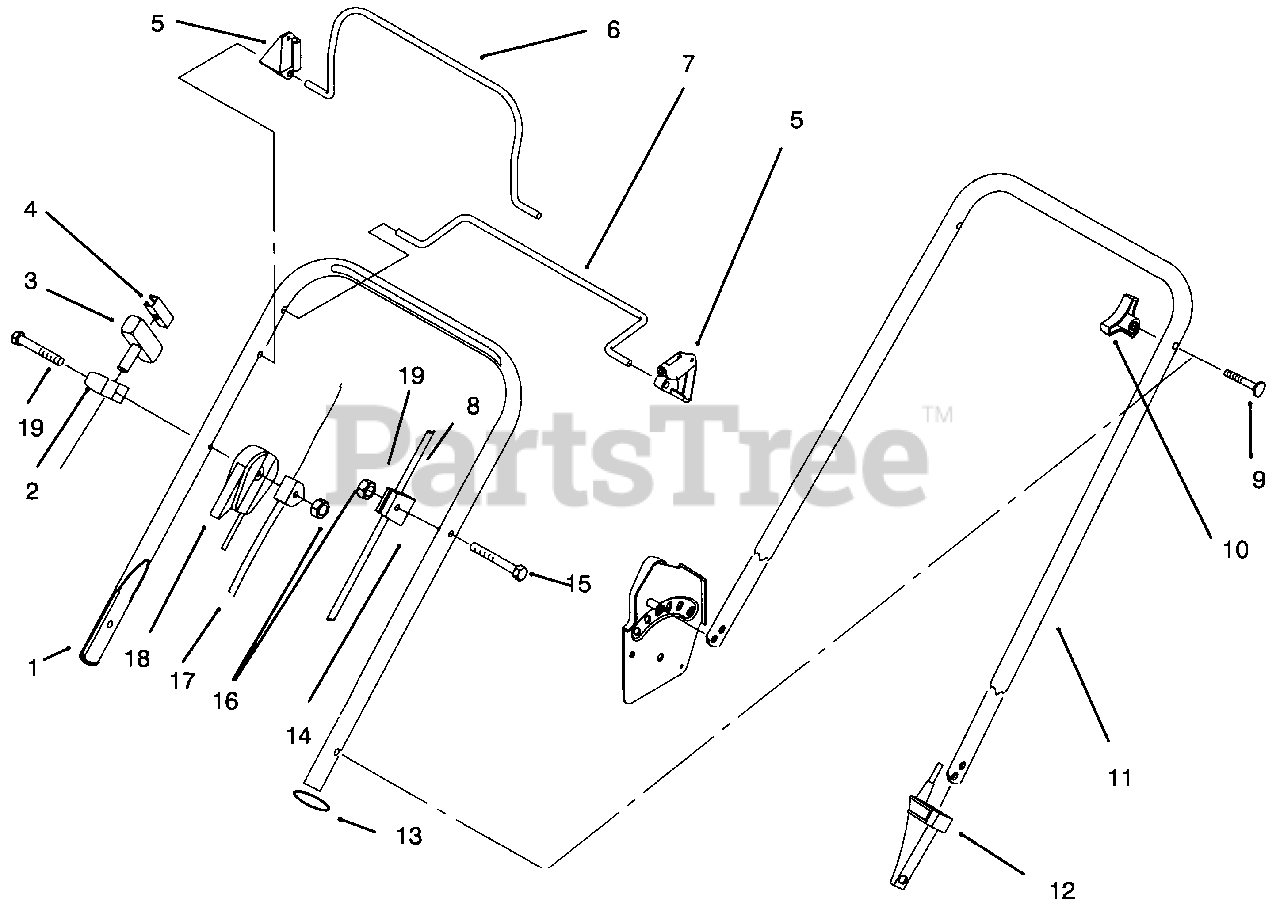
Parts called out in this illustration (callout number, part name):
1	Handle-Upper
2	Guide-Rope
3	Handle-Starter
4	Clip-Rope Insert
5	Stop-Pivot
6	Bail-Brake
7	Bail-Control (Self Propelled)
8	Cable-Traction
9	Screw-Handle
10	Knob-Handle
11	Handle-Lower
12	Anchor-Cable, (Lower)(Self Propelled)
13	Tie Strap
14	Anchor-Cable, (Upper)(Self Propelled)
17	Cable-Brake
18	Cable-Throttle
